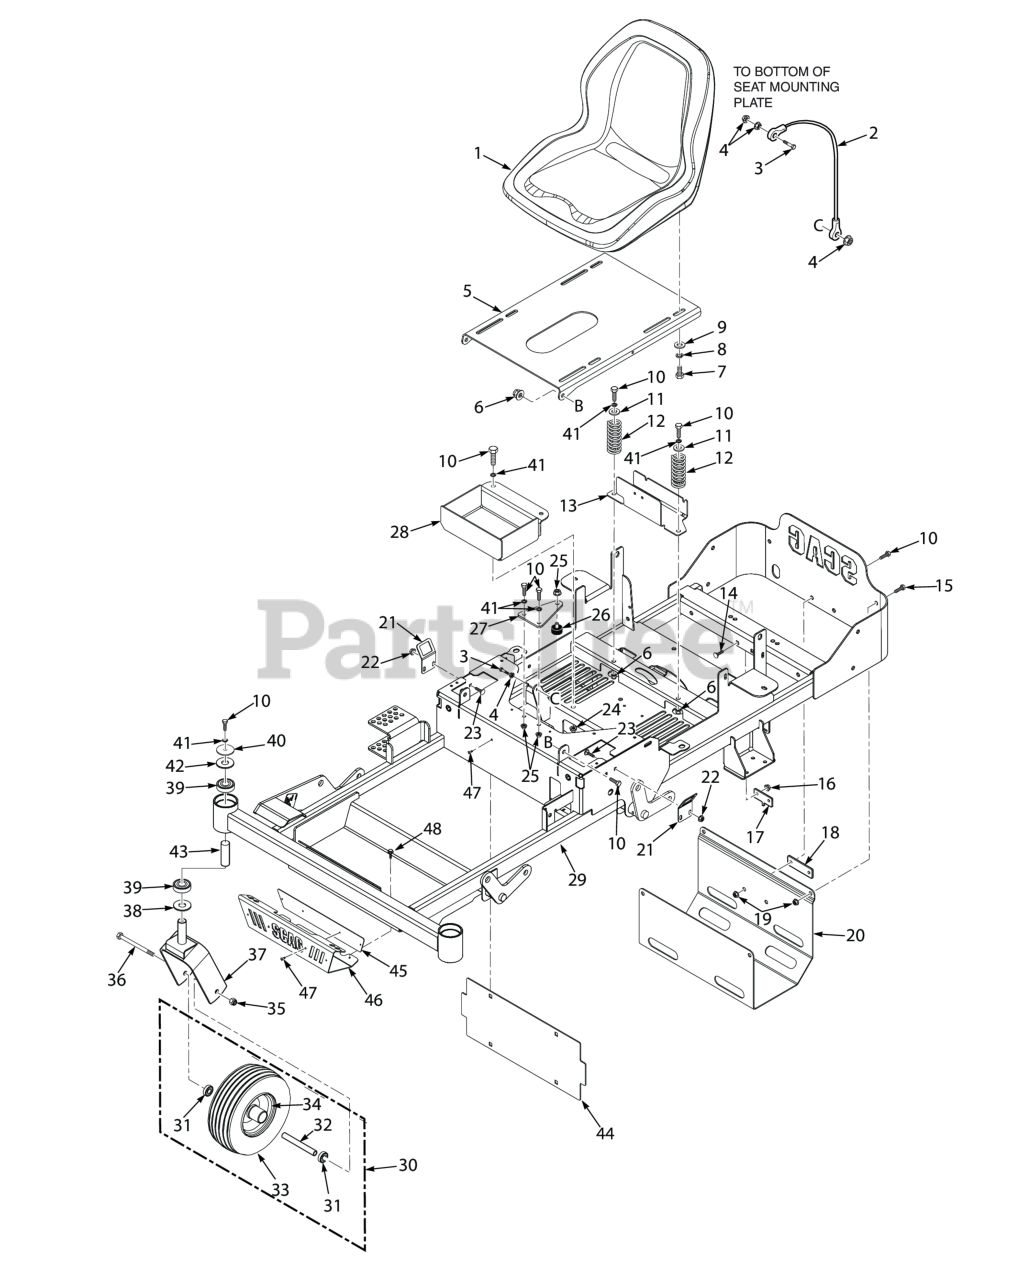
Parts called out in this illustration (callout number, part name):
1	Seat, SZL
2	Cable, Seat Stop
3	SERR. FLG. HEX HEAD CAPSCREW, 5/16-18 X 3/4
4	NUT, 1/4-20 SERRATED FLANGE HEX HEAD
5	Seat-Plate W/Decal
6	Nut, Flange Elastic Stop Nut, 3/8-16
7	Bolt, Heax Head 5/16-18 x 1" (48V / 52V)
8	Lockwasher, 5/16 (.317 x .586 x .078) Helical Spring
9	Flatwasher, 5/16-.375 x .875 x .083 (35BV & 37BV-EFI)
10	Bolt, Hex Head, 3/8-16 x 1 Gr. 5
11	Flatwasher, 3/8" Special (.391 x .938 x .105)
12	Spring, Seat
13	Seat Stop
14	Bolt, 5/16-18 x .75 RHSN Carriage
15	Bolt, Hex Head, 3/8-16 x 3/4"
16	Nut, Flange Head Elastic Stop 5/16-18
17	Plate, Anti-Rotation
18	Plate, Spacer
19	NUT, 3/8-16 SERRATED FLANGE HEX HEAD
20	Skid Plate, SZL-36
21	Bracket, Switch
22	Nut, Flanged Elastic Stop 1/4-20
23	Serr. Fl. Hex Head CPSCR, 1/4-20 x 3/4"
24	Threaded insert, Hex Head (Pressed)
25	Threaded insert, Hex Head (Pressed)
26	Bumper, Rubber 5/16-18 x 5/8"
27	Battery Hold Down
28	Battery Box
29	Frame Assembly, SZL-36H & SZL42H
30	Caster Wheel Assembly
31	Bearing
32	Spacer, Wheel Bearings
33	Tire, 11 x 4-5.00 2-Ply
34	Rim Assembly
35	HEX LOCKNUT, ELASTIC STOP, 1/2-13
36	Bolt, Hex Head 1/2-13 x 6-1/2" (52V)
37	Caster Assembly
38	Spacer, Yoke
39	Bearing
40	Flatwasher, 3/8-.406 x 2.25" x .1875
41	Lockwasher, 3/8" Spring, Kawasaki FX / FT & FT-EFI / B&S 32BV
42	Flatwasher, 7/16" (.500 x 1.25 x .083")
43	Spacer, Caster Bearing
44	Plate, Backing
45	Plate, Decal
46	Bumper. Front
47	Rivot, 3/16 x .402 POP
48	Screw, 1/4-20 x .375"
